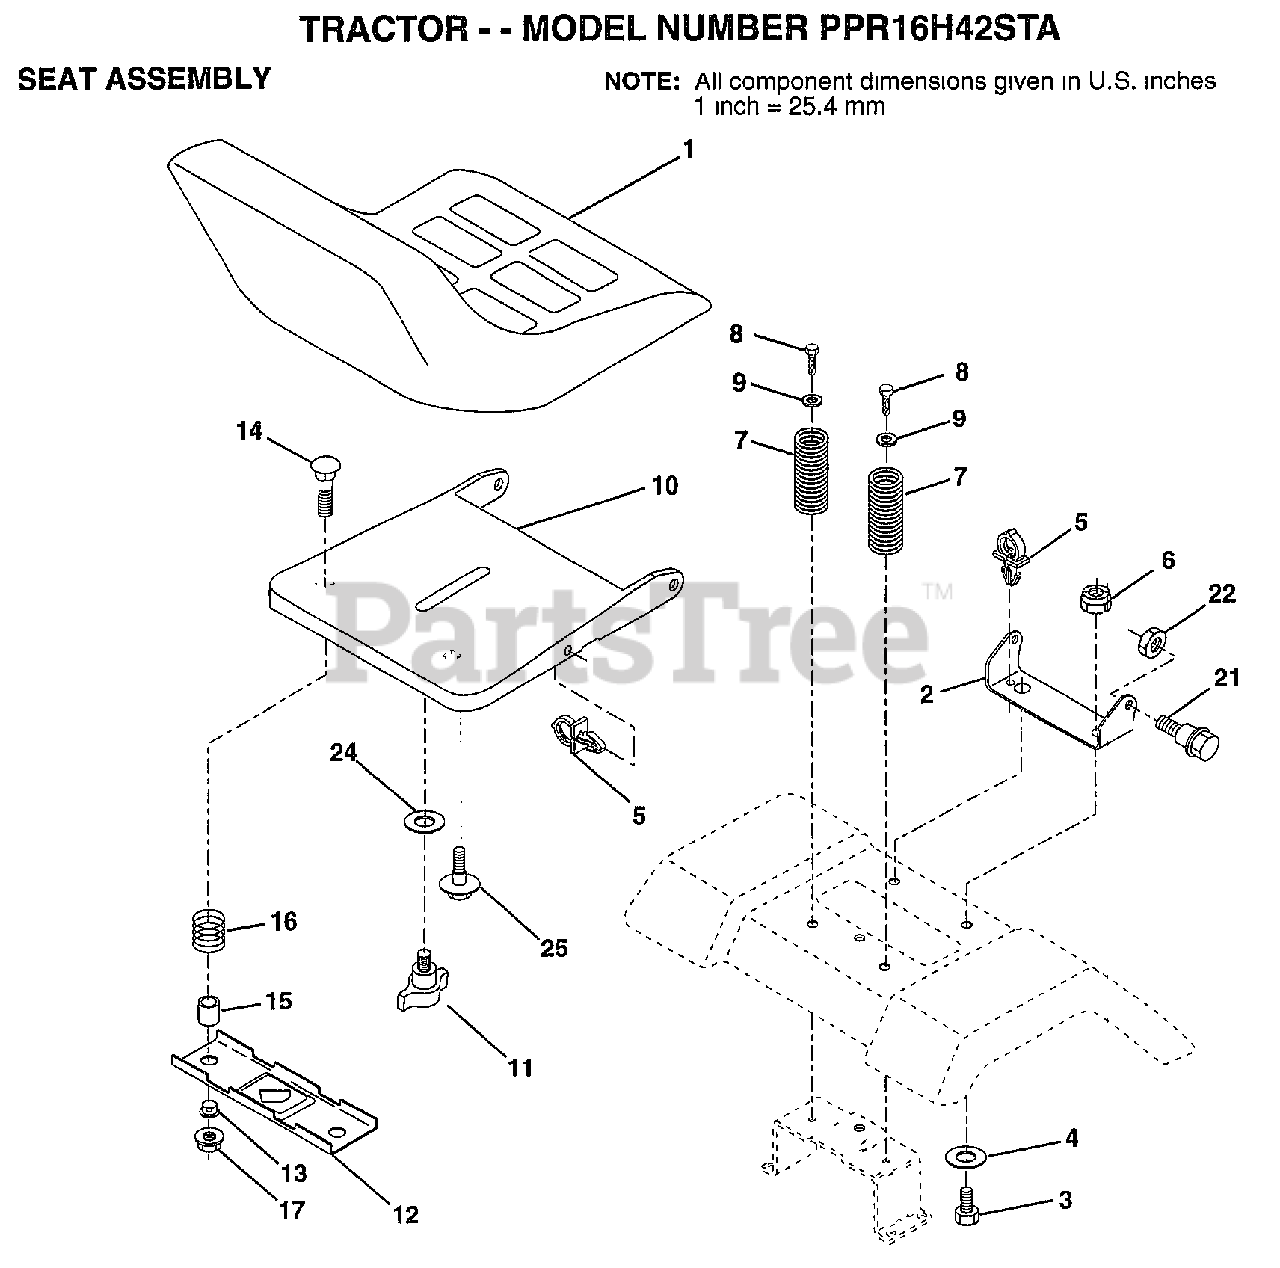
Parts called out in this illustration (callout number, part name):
1	SEAT.2400/1416.BK
2	BRACKET PVT SEAT
3	BOLT
4	WASHER PM
5	CLIP.PUSH-IN.HING
6	NUT
7	SPRING COMPRESSIO
8	SCREW GTV
9	WASHER
10	PAN-SEAT
11	KNOB.SEAT.ADJ.WINGNUT
12	BRKT SWITCH
13	BUSHING
14	BOLT-RD HD SQ NK
15	SPLIT SPACER
16	SPRING
21	"BOLT,SHOULDER"
22	NUT
24	WASHER
25	"BOLT,SHOULDER"
